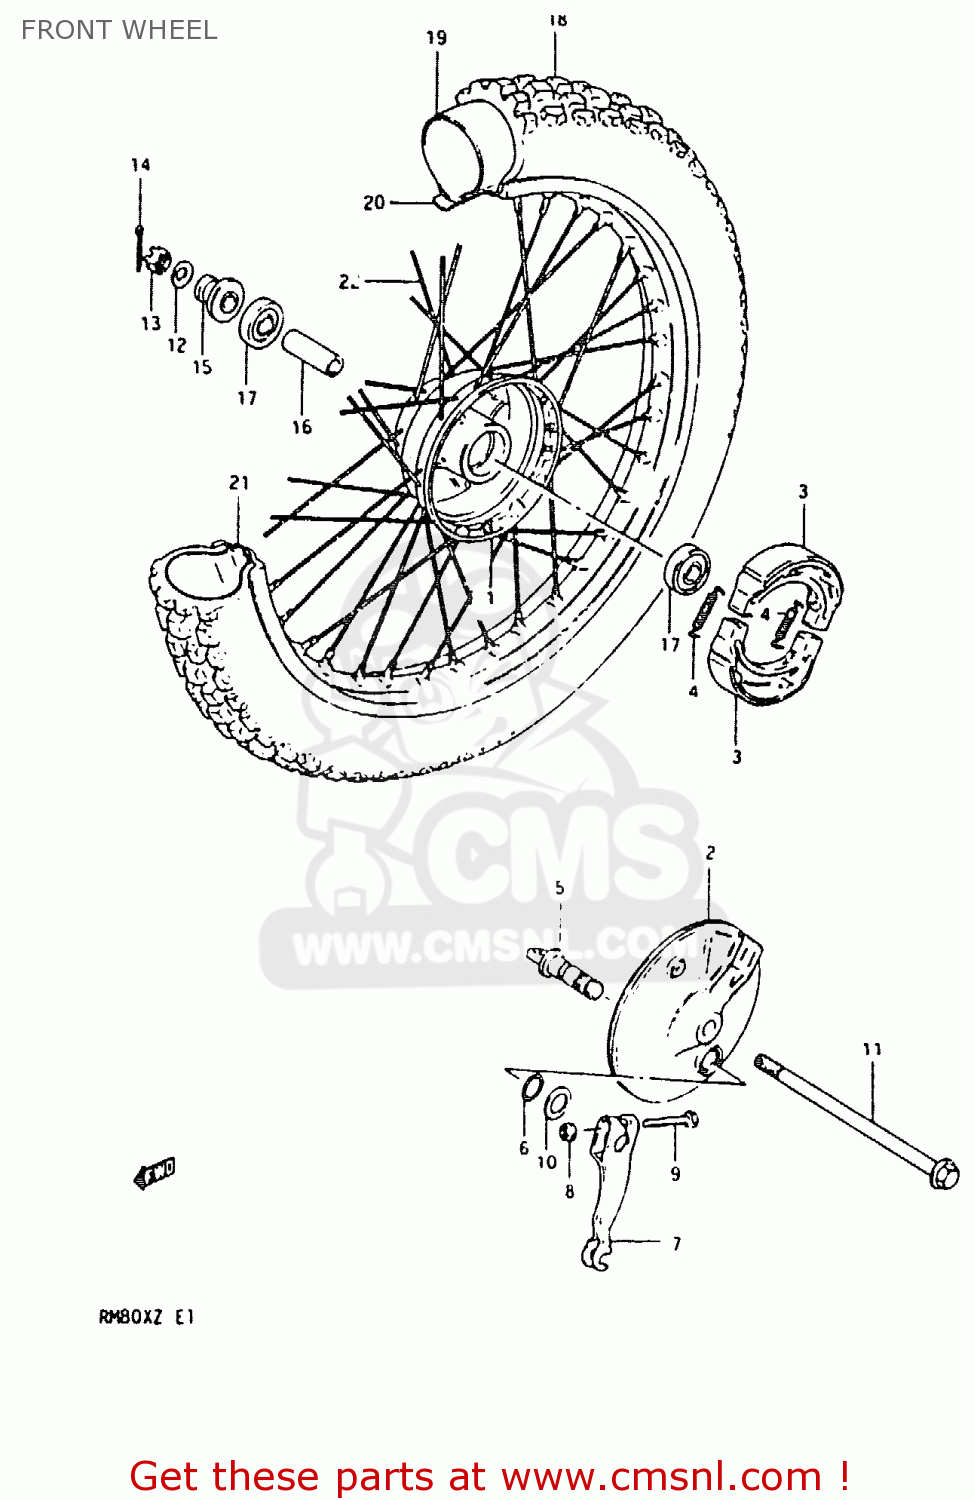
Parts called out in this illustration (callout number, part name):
1	HUB,FRONT
2	PANEL,FRONT HUB
3	SHOE,BRAKE
4	SPRING(L:34)
5	CAM,FRONT BRAKE
6	O RING(D:2.5,ID:11.4)
7	LEVER,FRONT BRAKE CAM
8	NUT
9	BOLT
10	WASHER(12.5X20X1)
11	AXLE,FRONT
12	WASHER
13	NUT
14	PIN 20X20
15	SPACER,FRONT AXLE,RIGHT
16	SPACER (10.4X15X48)
17	BEARING
18	TIRE,FRONT
19	TUBE,INNER
20	PROTECTOR,WHEEL,INNER
21	RIM,FRONT WHEEL
22	SPOKE SET,FRONT
